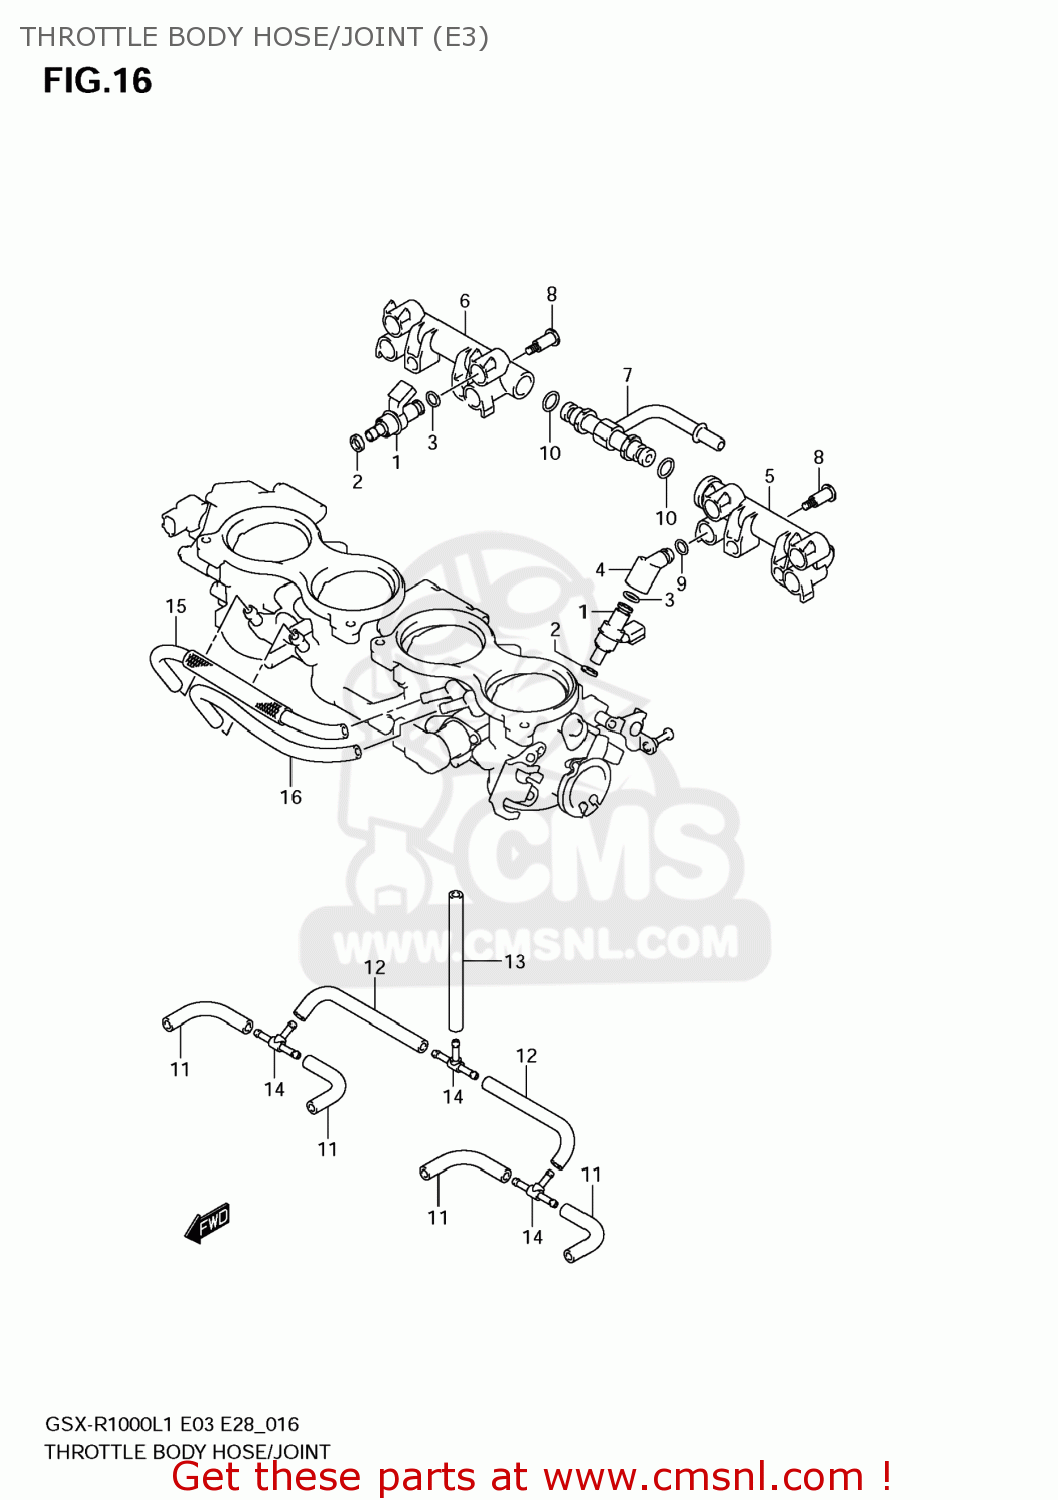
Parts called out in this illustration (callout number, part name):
1	INJECTOR ASSY
2	RING,SEAL
3	O RING
4	PIPE,FUEL
5	PIPE,FUEL
6	PIPE,FUEL
7	JOINT
8	SCREW
9	O RING
10	O RING
11	HOSE
12	HOSE
13	HOSE,RUBBER(L:100)
14	JOINT
15	TUBE
16	TUBE
